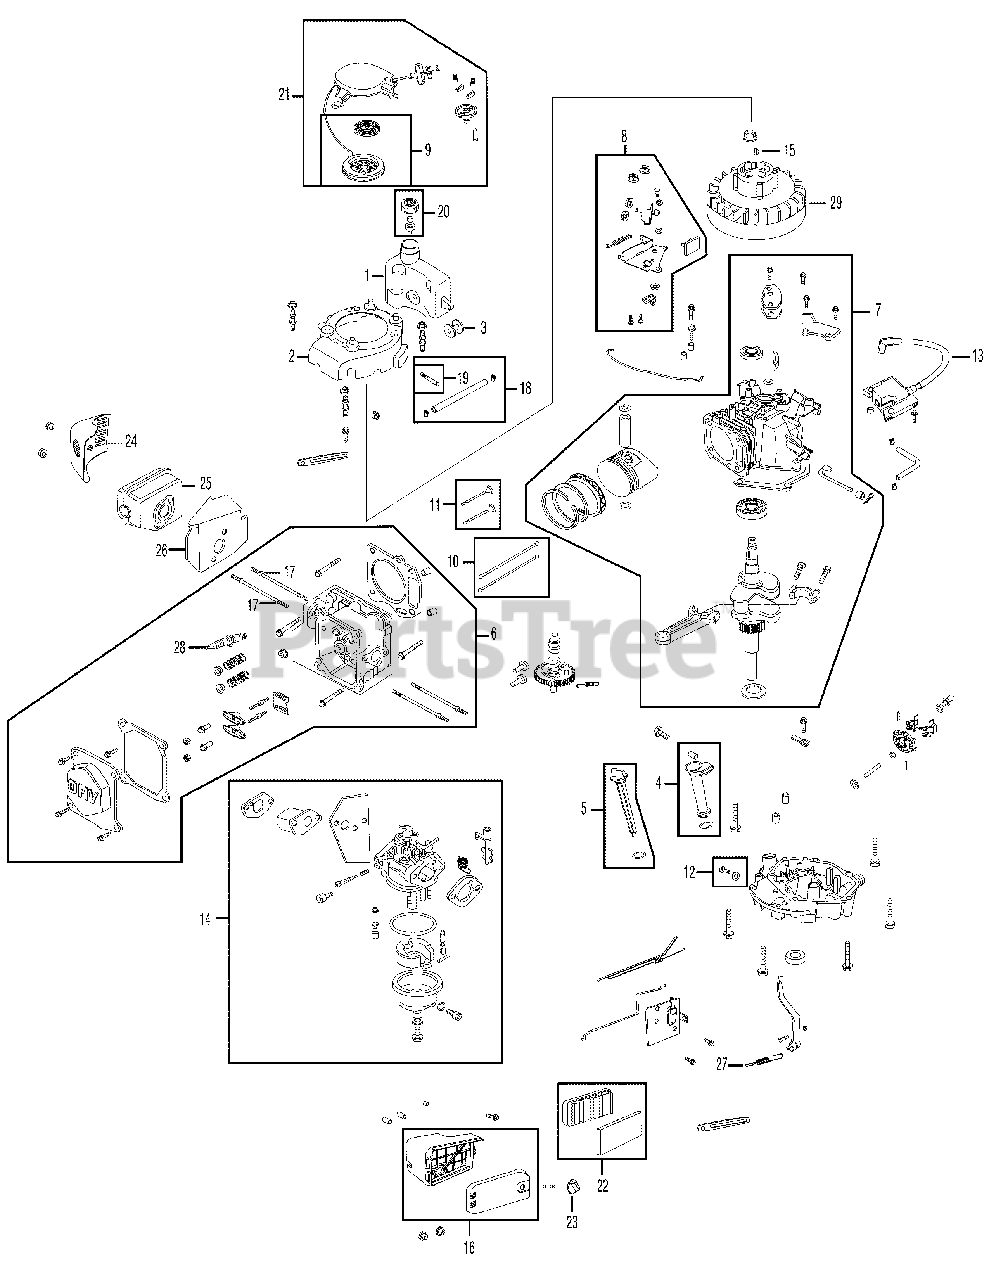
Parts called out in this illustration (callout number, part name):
1	Fuel Tank
2	Flywheel Shroud
2	Screw
3	Rubber Fuel Tank Mounting Washer
4	Oil Filler Tube Assembly
5	Dipstick Assembly
6	Cylinder Head Complete
7	Short Block Assembly
8	Stop Switch and Brake Assembly
9	Recoil Spring and Pulley Assembly
10	Push Rod Kit
11	Valve Kit
12	Oil Drain Plug and Washer Assembly
13	Ignition Coil
14	Carburetor Assembly
15	Flywheel Key
16	Air Cleaner Housing Assembly Complete
17	Muffler Stud Assembly
18	Fuel Line Kit - Inc. hoses, clamps & filter
19	Fuel Filter
20	Fuel Cap Assembly
21	Recoil Starter Assembly
22	Air Cleaner Kit
23	Air Cleaner Thumb Screw
24	Muffler Guard
25	Muffler
26	Muffler Gasket /Heat Shield
27	Governor Return Spring
28	Spark Plug
29	Flywheel
